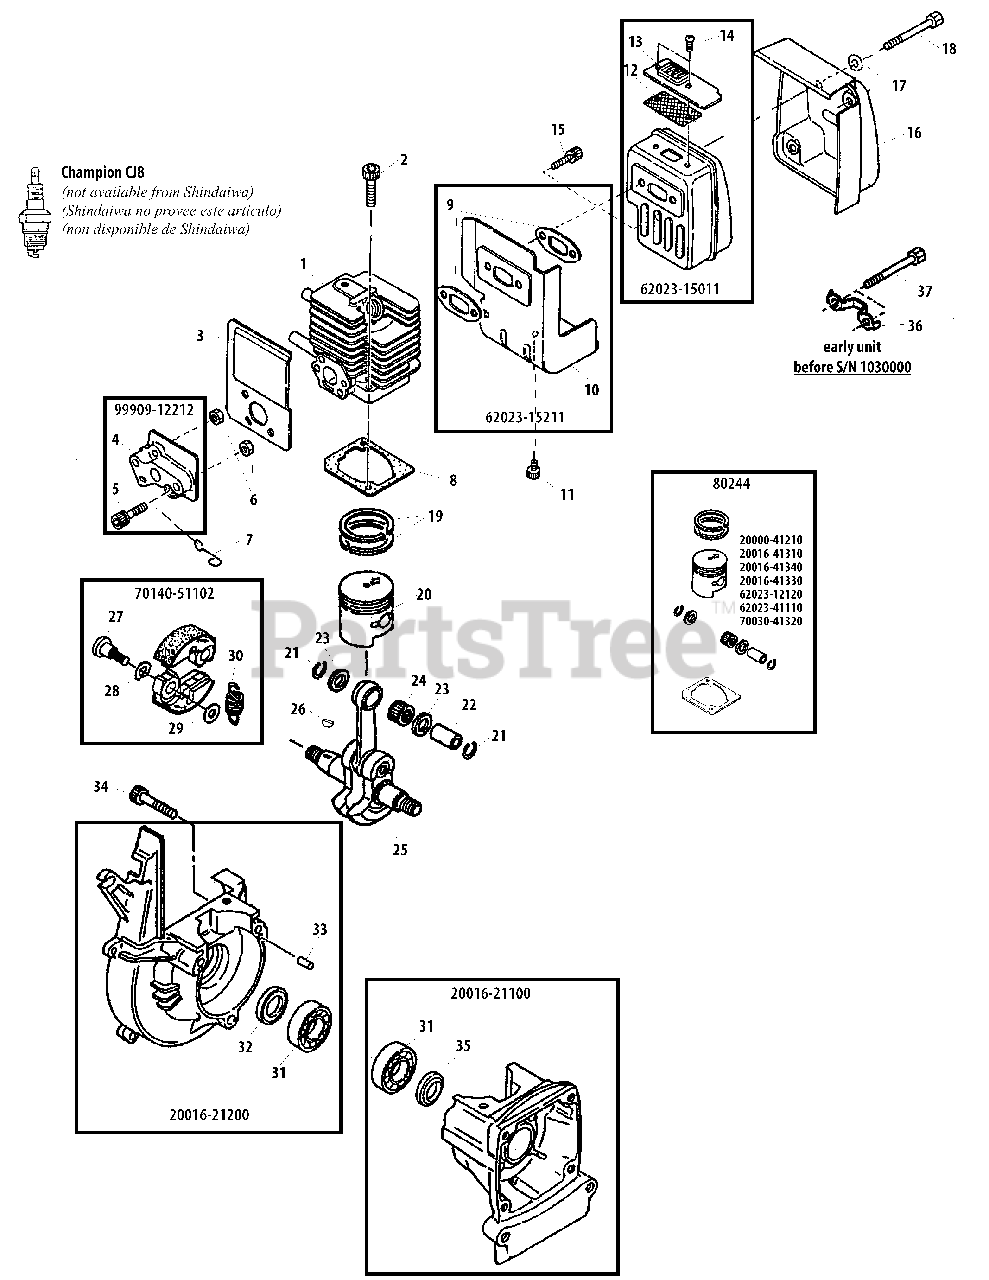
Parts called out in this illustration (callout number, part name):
1	CYLINDER
2	BOLT 5×25
3	HEAT SHIELD, INTAKE
4	INSULATOR
5	BOLT SS M5×30
6	NUT M5×6.3
7	CLIP, VENT ASSY
8	GASKET, CYLINDER
9	GASKET, EXHAUST
10	HEAT SHIELD, EXHAUST
11	BOLT 5×8
12	SCREEN, SPARK ARRESTER
13	OUTLET, EXHAUST
14	SCREW M4×6
15	BOLT 5×20
16	COVER, EXHAUST
17	WASHER SS 5 MM
18	BOLT M5×60
19	RING, PISTON
20	PISTON
21	RING, SNAP
22	PIN, PISTON
23	WASHER, THRUST
24	BEARING, NEEDLE
25	CRANKSHAFT
26	KEY, WOODRUFF 3×10
27	BOLT, CLUTCH
28	WASHER, SPRING
29	WASHER 6 MM
30	SPRING, CLUTCH
31	BEARING, BALL 6001 C3
32	SEAL, OIL 12
33	PIN, LOCATING Ø4×8
34	BOLT 5×25
35	SEAL, OIL 12
36	PLATE, LOCK
20016-21100	CRANKCASE ASSY, S
20016-21200	CRANKCASE ASSY, M
62023-15011	MUFFLER ASSY
70140-51102	CLUTCH ASSY
80244	PISTON ASSY
99909-12212	INSULATOR ASSY
